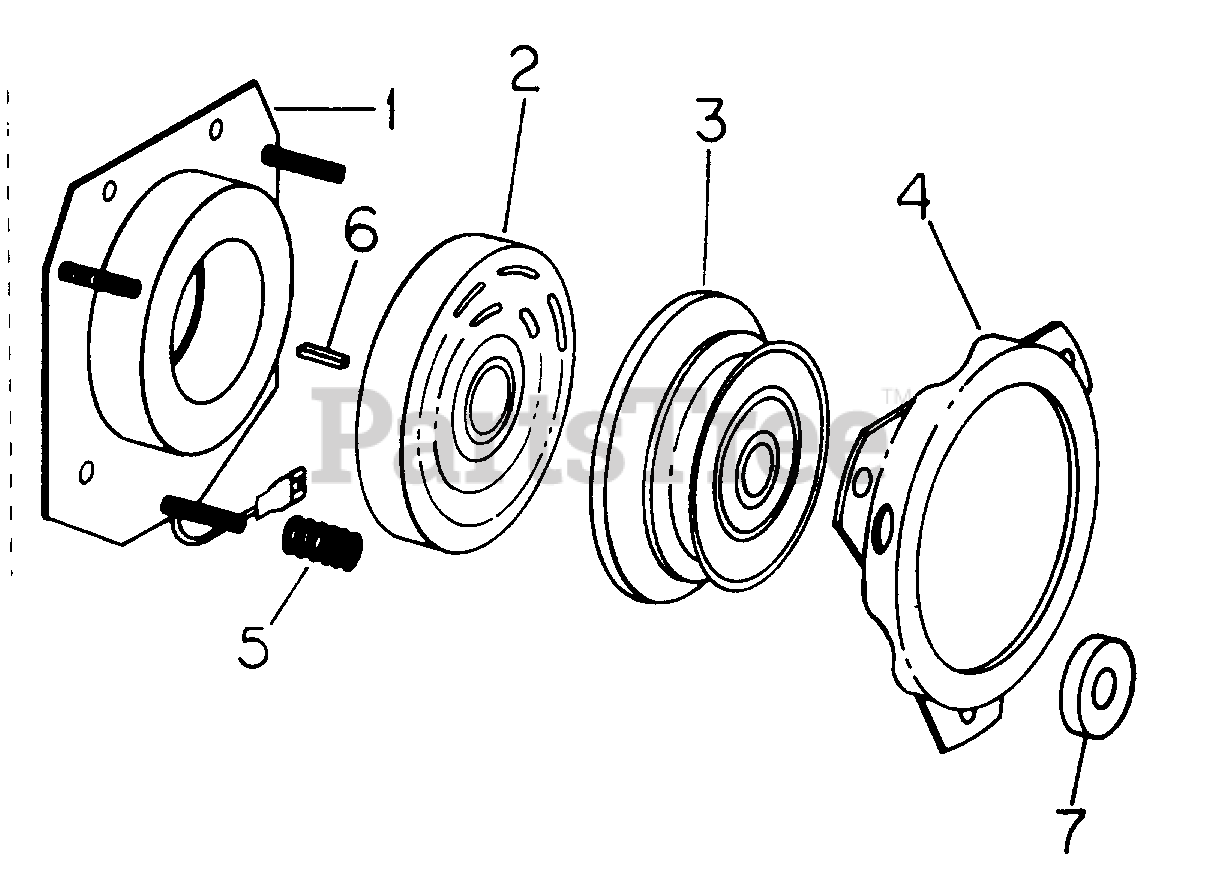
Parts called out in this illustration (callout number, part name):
2	Armature Assy
3	Field Assy
5	Kit, Spring w/Nut
6	Key, 1/4 X .75 Sq Parallel
7	Washer, Weight Balance
